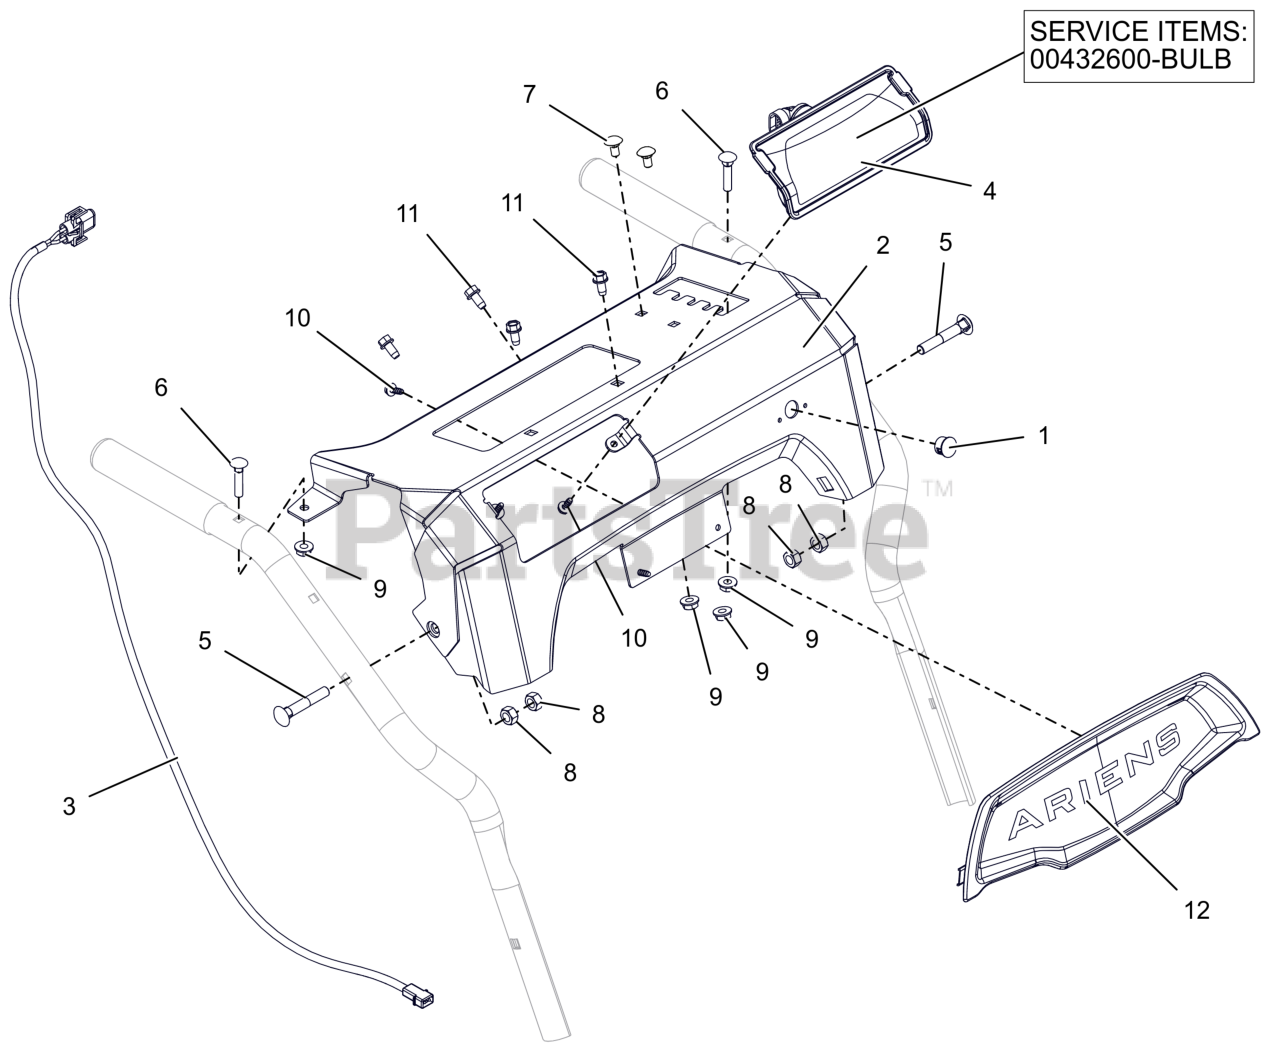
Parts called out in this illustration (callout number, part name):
1	HOLE PLUG, PLASTIC .56 HOLE
2	CTRL PANEL W/DECAL-COMP REMOTE
3	HARNESS, LIGHT - COMPACT
4	HEADLIGHT ASY, HALO 20W 2SHOT
4	BULB, LIGHT-HALOGEN 20W
5	BLT-RDHDXLSQNK .31-18X2.0 G5YZ
6	BLT-RDHDXLSQNK.25-20X1.25 G5ZC
7	BLT, RHSN .25-20X.500 G5 ZCC
8	NUT,LK-CTR .31-18 GA ZCC
9	NUT-LK-TOP-FLG .250-20 GF ZCC
10	SCR, PLASTIC #10X.50
11	SCR-TAP .25-20X.50 HWH ZCC
12	BEZEL, DASH - ARIENS SM DASH
